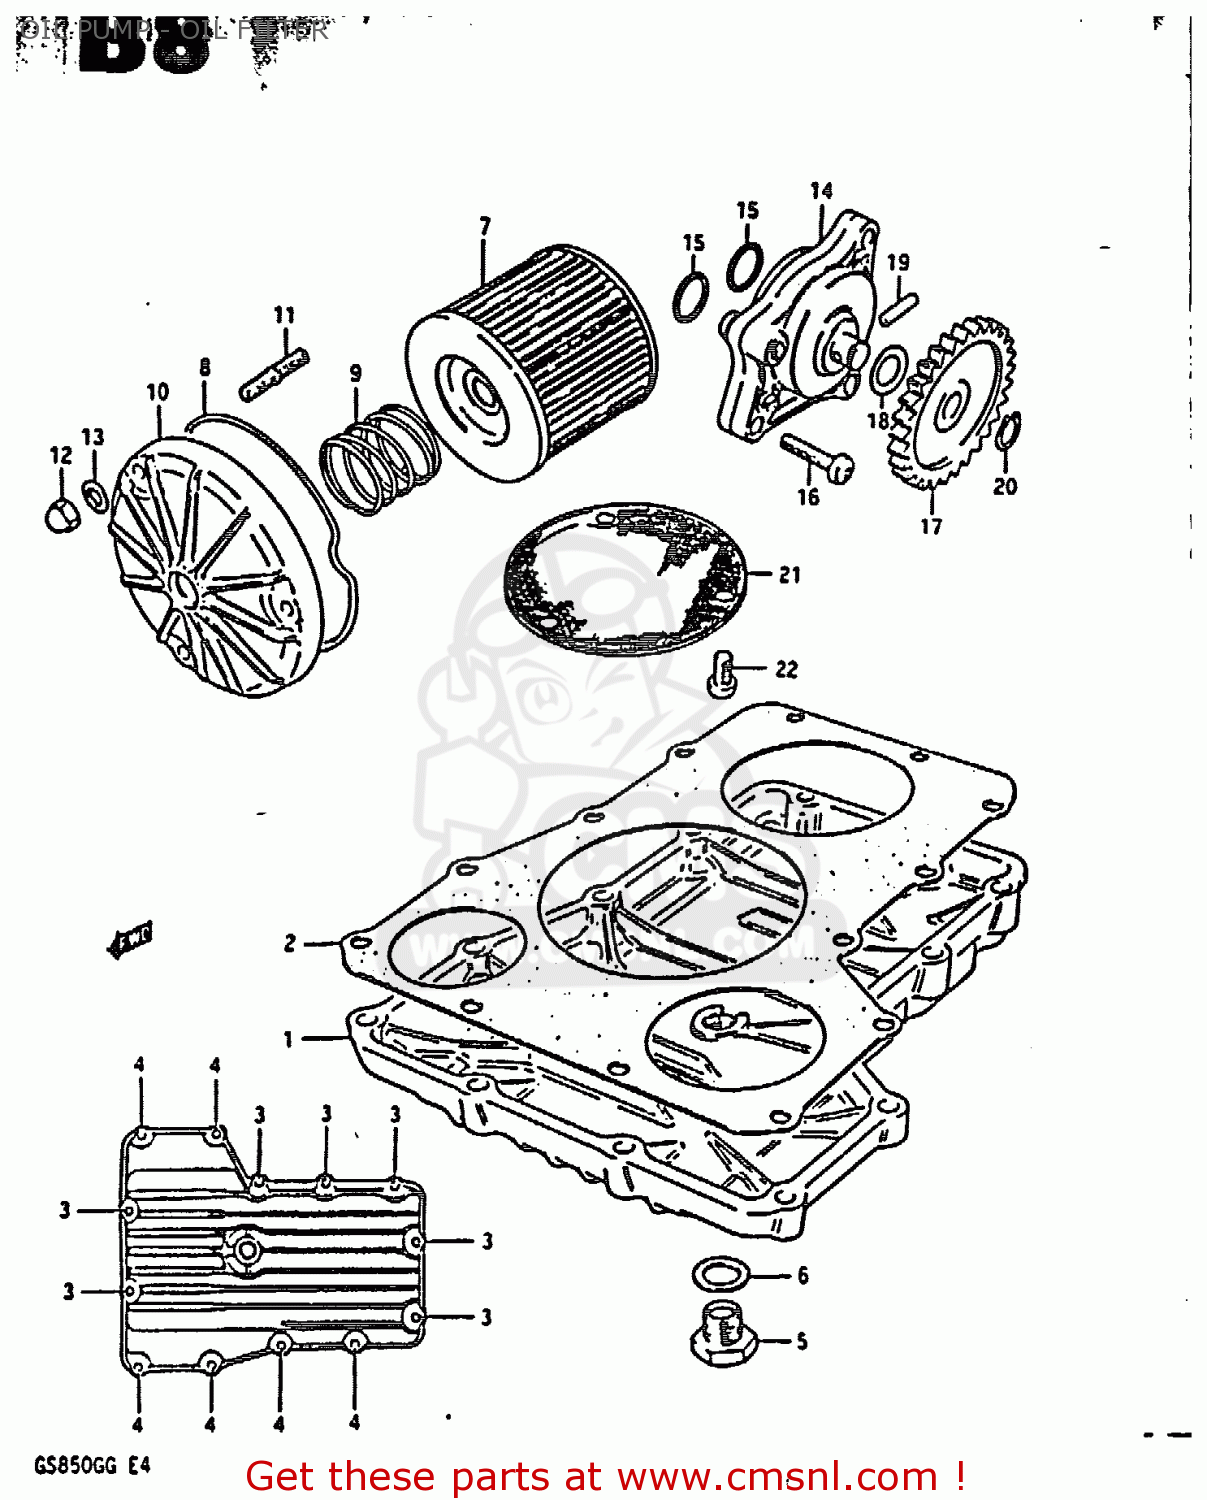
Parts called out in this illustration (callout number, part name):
1	PAN,OIL
2	GASKET,OIL PAN (MCA)
3	BOLT 6X30
4	BOLT
5	PLUG
6	GASKET(14X19.2X2) (NAS)
7	FILTER ASSY,ENGINE OIL
8	O RING,OIL FILTER CHAMBER CAP
9	SPRING
10	CAP,OIL FILTER
11	STUD 6X20
12	NUT 6MM
13	WASHER
14	PUMP ASSEMBLY,ENGINE OIL
15	O RING(D:1.9,ID:13)
16	SCREW
17	GEAR,ENG OIL PUMP DRIVEN(NT:33
18	SHIM
19	PIN(4X15.8)
20	CIRCLIP
21	STRAINER,ENGINE OIL
22	SCREW 6X12
